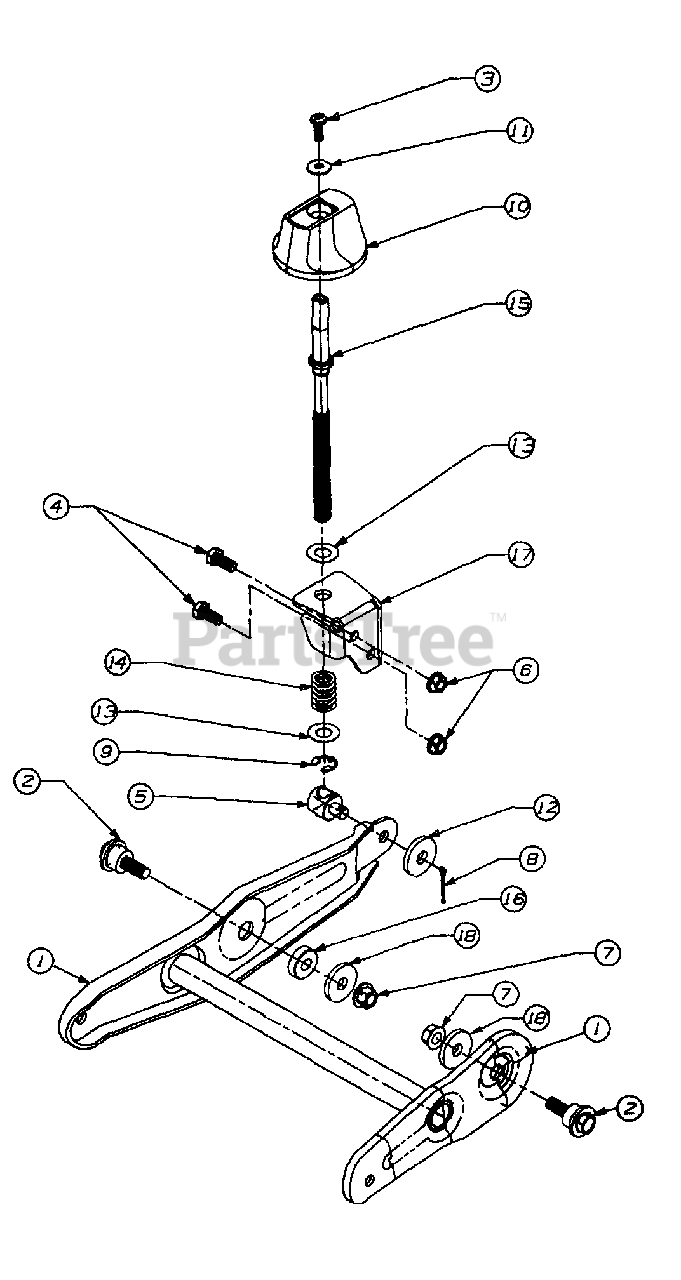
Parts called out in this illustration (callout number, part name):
3	SCREW-MACHINE PAN HD.
4	SCREW-HEX
5	FERRULE-ADJUSTABLE
6	NUT-HEX FLANGE
7	NUT-HEX FLANGE LOCK
8	PIN-COTTER
9	E-RING
10	PLASTIC KNOB
11	BELL WASHER
12	FLAT WASHER
13	FLAT WASHER
14	COMPRESSION SPRING
15	ADJUSTABLE ROD
16	SPACER
